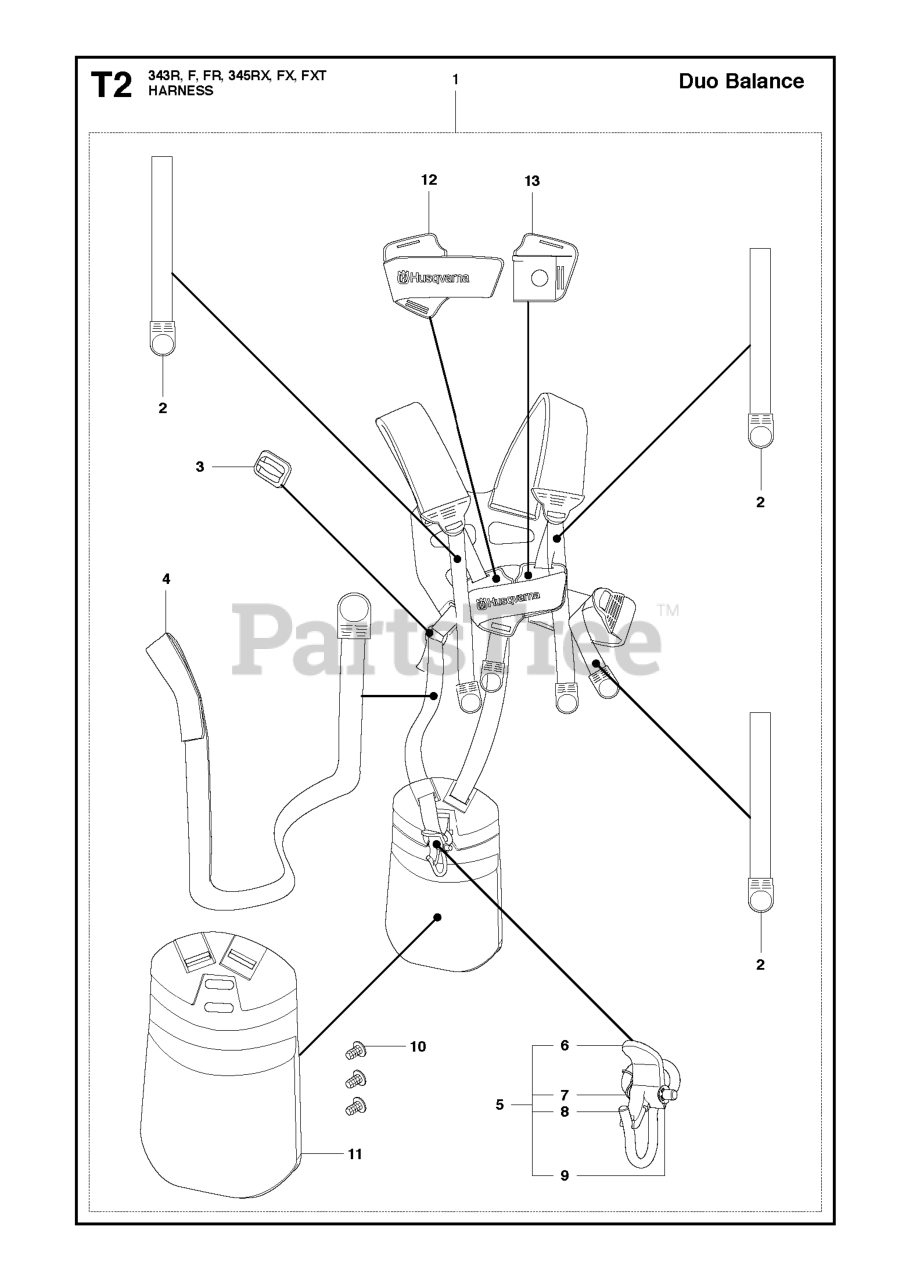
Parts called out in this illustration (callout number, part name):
1	Harness
1	Duo-Bal Harness
3	RP CLIP
5	HARNESS HOOK, COMPLETE
6	CATCH *
7	SPRING
8	HOOK
12	FRONT PIECE
13	FRONT PIECE
